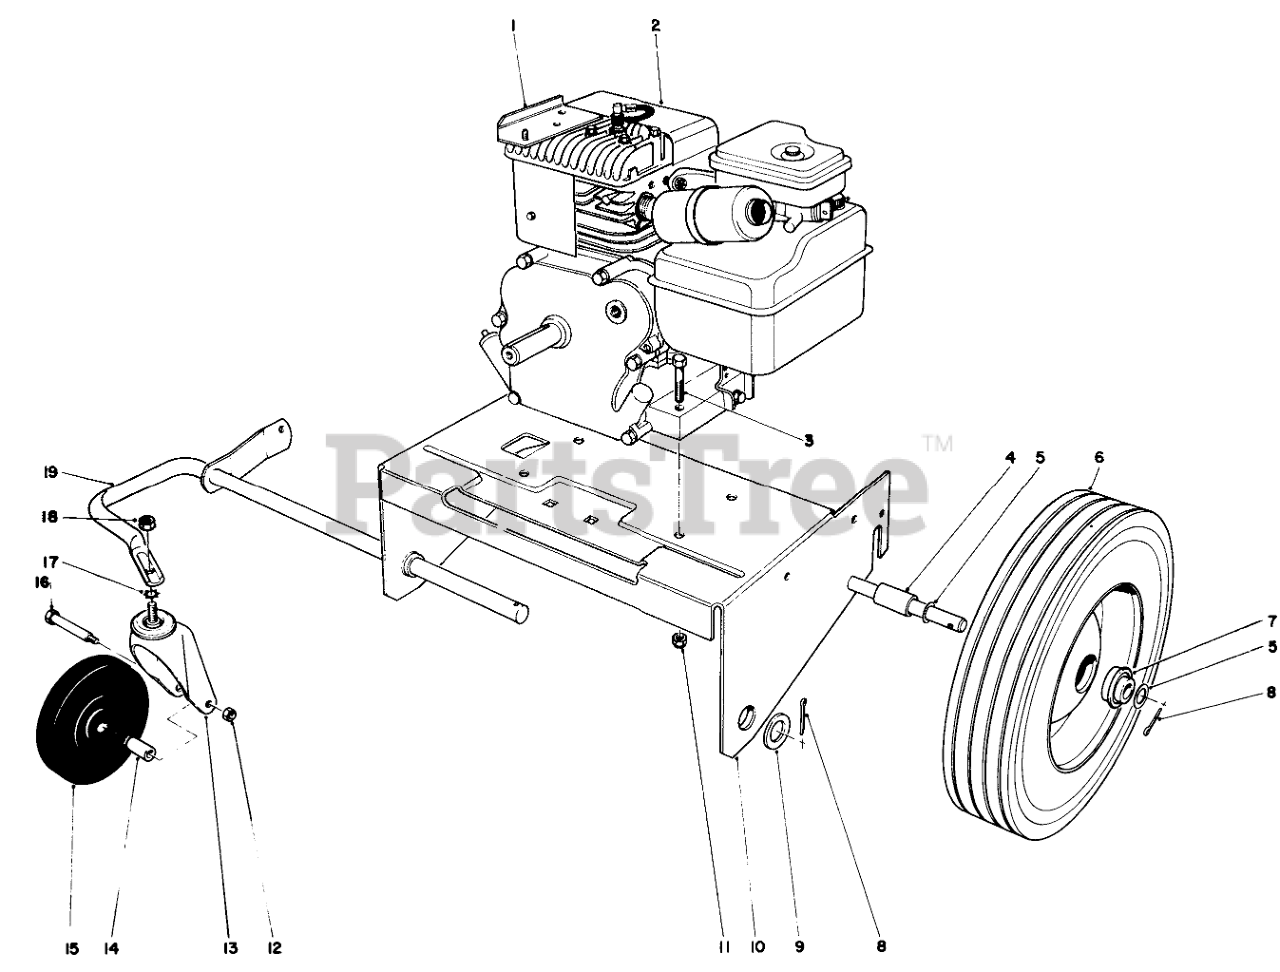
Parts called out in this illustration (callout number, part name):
1	MOUNTING BRKT WA
2	Engine
3	SCREW-HH
4	SPACER-AXLE
5	WASHER
6	WHEEL
7	BEARING
8	PIN-COTTER
9	WASHER-FLAT
10	Engine Plate
11	NUT-LOCK, NI
14	Wheel Bushing
15	Wheel
17	WASHER-LOCK
19	Front Wheel Support
